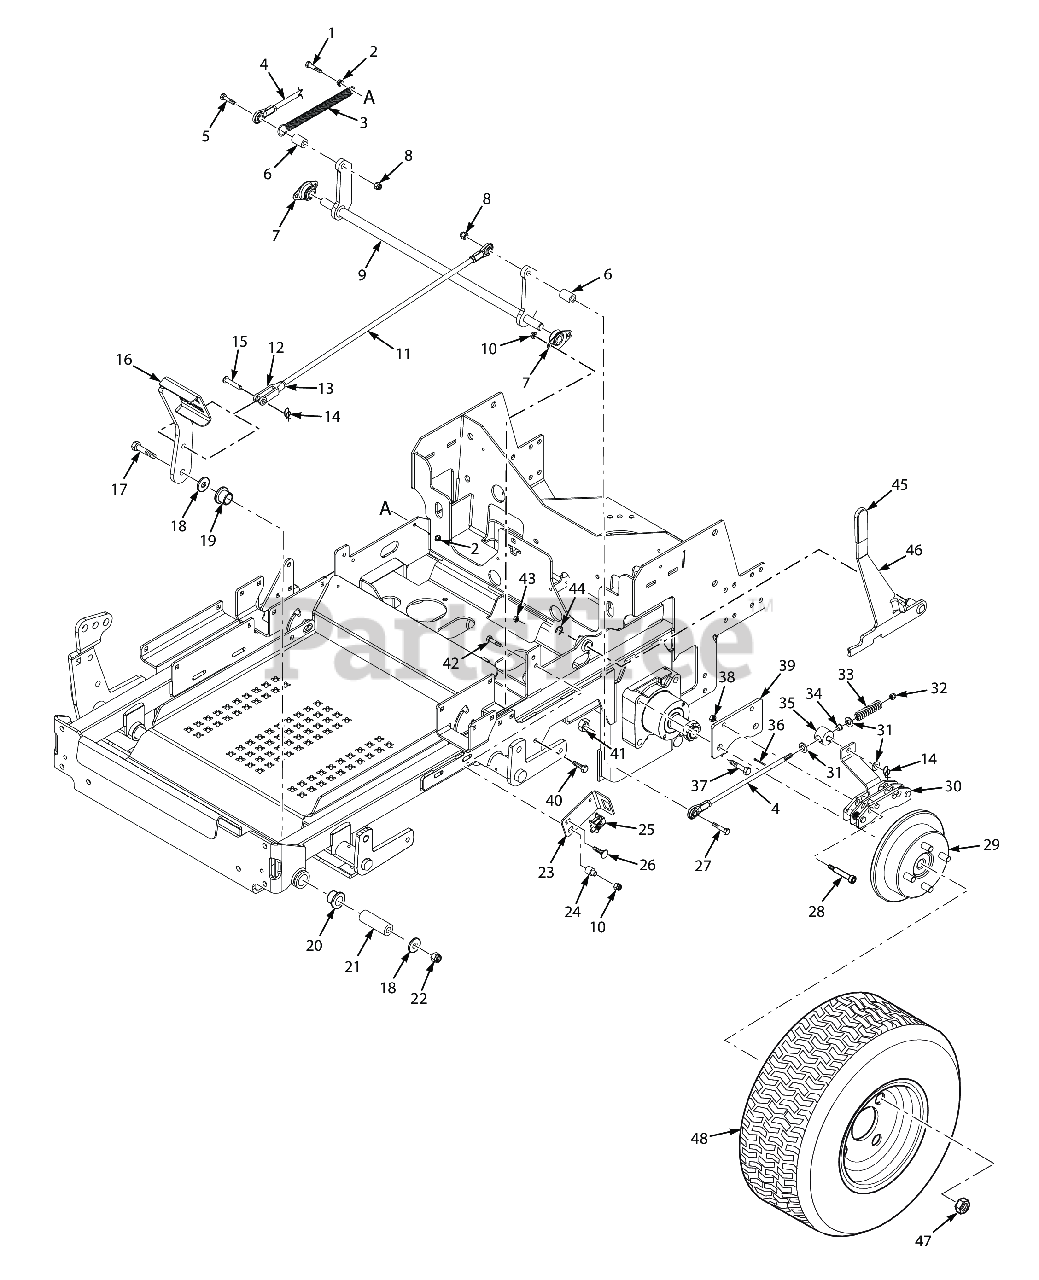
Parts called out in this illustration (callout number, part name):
1	SERR. FLG. HEX HEAD CAPSCREW, 5/16-18 X 3/4
2	NUT, 1/4-20 SERRATED FLANGE HEX HEAD
3	Spring, Brake Return
4	Brake Link Assembly
5	Capscrew, Hex Head 3/8-16 x 2-1/2"
6	Yoke, Front Caster Wheel
7	Bearing, Self Aligning - 5/8 I.D.
8	Nut, Flange Elastic Stop Nut, 3/8-16
9	Brake Bellcrank Weldment
10	HEX NUT, ELASTIC STOP LOCK, 5/16-18
11	Brake Rod Assembly
11	Rod End, 3/8-24 LH Thread Female
11	Nut, 3/8-24 UNF-2B LH Thread
12	Clevis, Traction Control
13	Nut, 3/8-24 UNF R.H. Thread
14	Pin, Rue Cotter 3/8" Diameter
15	Pin, Clevis 3/8-16 x 1-1/16"
16	Brake Pedal Weldment
17	Bolt, Hex Head 1/2-13 x 4-1/4"
18	Flat Washer, 1/2 (.562 x 1.375 x .109)
19	Sleeve, Brake Pivot
20	Bearing, Plastic
21	Sleeve, Brake Pivot
22	HEX LOCKNUT, ELASTIC STOP, 1/2-13
23	Switch Mounting Bracket, Brake
24	Spacer, Pump Dampener
25	Switch, Interlock, Normally Open
26	Serr. Fl. Hex Head CPSCR, 1/4-20 x 3/4"
27	Bolt, Hex Head 3/8-16 x 3" - 52"
28	Bolt, Shoulder 1/2 x 3/8-16 x 2-3/4"
29	Wheel Hub w/Disc
30	Brake Caliper
31	Flatwasher, 3/8 (.406 x .812 x .065)
32	Nut, Elastic Stop 3/8-16, grade 8 black
33	Spring, Brake
34	Bearing
35	Swivel Assembly, Brake
36	Pin, Cotter 3/32 x .75"
37	Bolt, Hex Head 1/2-13 x 2-3/4" (48V & 52V - One Weight)
38	Bolt, Hex Head 3/8-16 x 1" Ser. Flg.
39	Mounting Bracket, Brakes
40	BOLT, SERRATED FLANGE HEX HEAD 5/16-18 X 3/4"
41	HEX NUT, ELASTIC STOP LOCK, 3/8-16
42	Bolt, Hex Head 5/16-18 x 1-1/2" - Front
43	HEX, NUT, ELASTIC STOP LOCK, 1/4-20
44	RETAINING RING, 5/8" EXTERNAL "E"
45	Grip, Brake Handle
46	Lever w/Grip, Parking Brake
47	Wheel Nut, 1/2-20 x 13/16
48	Wheel Assy 24 x 9.5-12 (48" Deck)
48	Wheel Assembly 24 x 12-12 (61" Cutter Deck)
48	Rim W/Valve Stem (48" & 52")
48	Tire, 24 x 12-12 Turf Master
